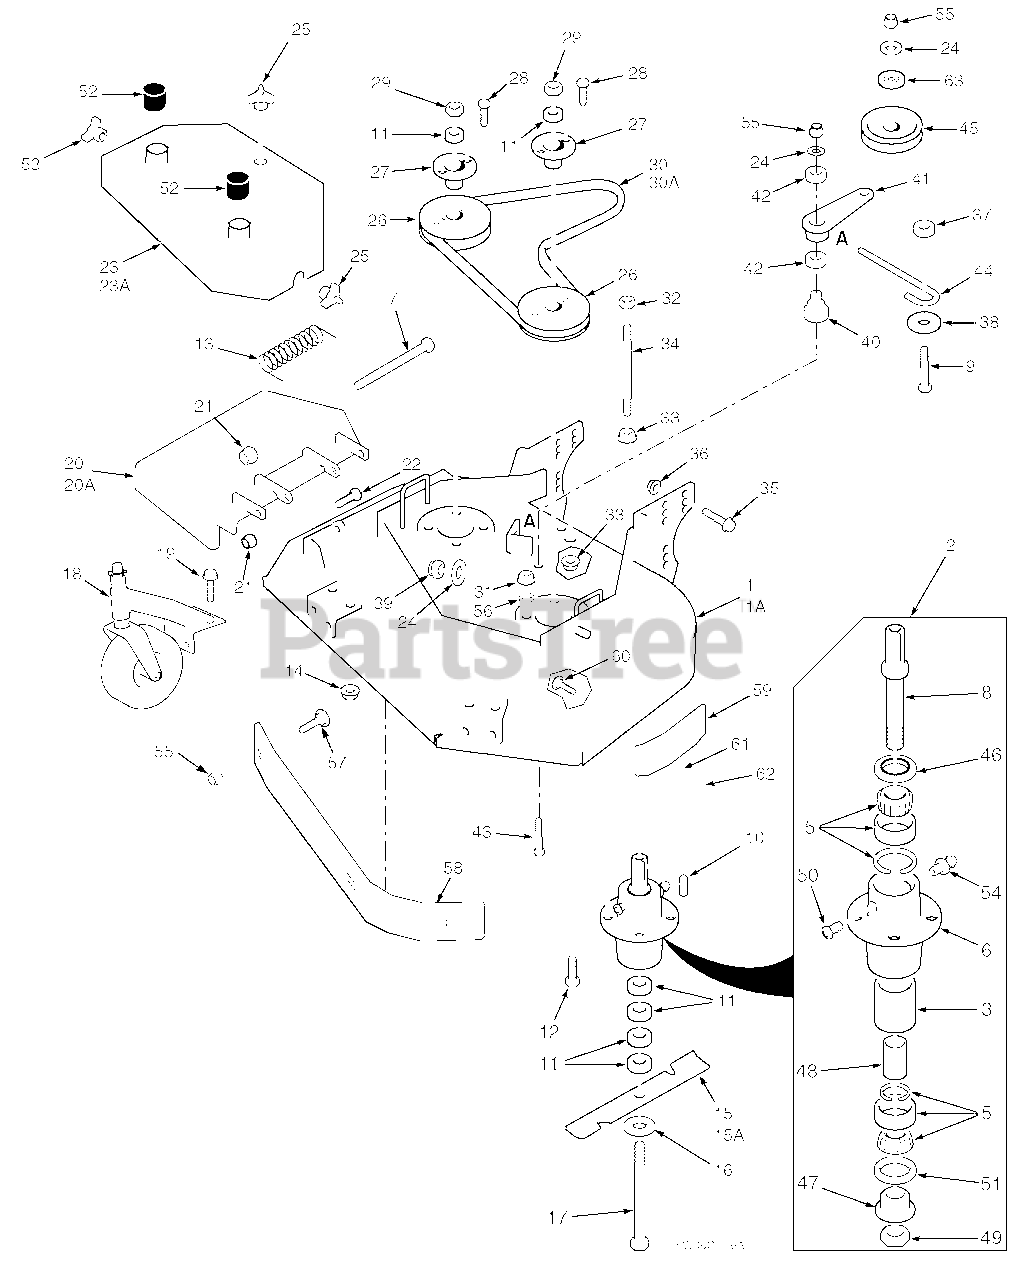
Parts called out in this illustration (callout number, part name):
1	Cutter Deck w/Decals
1A	Cutter Deck w/Decals
2	Cutter Spindle Assembly
3	Spacer, Outside
5	Bearing, Tapered
6	Spindle Housing
7	Bolt, 5/16-18 x 4-3/4"
8	Spindle Shaft
9	Bolt, 3/8-16 x 3-3/4" Hex Head
10	Key, 1/4 x 1/4 x 2"
11	Spacer, Cutter Blade - Small
12	Bolt, 5/16-18 x 1-1/2" Hex Head Grade 8
13	Spring, Chute Return
14	Nut 5/16-18 Serrated Flange
15	Cutter Blade, 16-1/2"
15	Cutter Blade, 18"
15A	Cutter Blade 16-1/2 Hi-Lift
15A	Cutter Blade, 18 Hi-Lift
16	Flatwasher, 5/8 W
17	Hex Hd. Bolt, 5/8-11 x 9-1/2"
18	Caster Assembly
19	Cpscrw,5/16-18 x 3/4" Ser. Flg. Hex Head
20	Discharge Chute
20A	Discharge Chute
21	Hex Nut, 5/16-18 Elastic Stop
22	Hex Hd Bolt, 5/16-18 x 1"
23	Belt Cover Assy
23A	Belt Cover Assy
24	Flat Washer, 3/8" Special
25	Wing Nut, 3/8-16
26	Pulley
27	Tapered Hub
28	Hex Hd. Bolt, 1/4-20 x 1"
29	Hex Nut, 5/8-11
30	Belt, Blade Drive
30A	Belt, Blade Drive
31	Elastic Stop Nut, 5/16-18 Grade 8
32	Hex Nut, 3/8-16 Center Locknut
33	Nut, 3/8-16 Serrated Flange
34	Support, Belt Cover
35	Cpscrw, 1/2-13 x 1"Ser.Flg. HH
36	Nut, 1/2-13 Spiralock
37	Spacer, J-Hook
38	Flatwasher, 3/8 x 1-1/2 x 16 GA
39	Elastic Stop Nut, 3/8-16
40	Idler Pivot
41	Idler Arm Assy.
42	Bearing
43	Cpscrw, 3/8-16 x 3-1/4" Hex Head
44	J-Hook
45	Idler Pulley, Belt Clutch
46	Seal, Cutter Spindle
47	Spindle Bushing
48	Spacer, Inside
49	Nut,1.06-18
50	Relief Fitting, Cutter Spindle
51	Seal, Cutter Spindle
52	Spindle Shield
53	Wing Nut, 3/8-16 (Small) RH side
54	Grease Fitting
55	Nut, Hex Elastic Stop 3/8-16
56	Lock Washer, 5/16"
57	Bolt, Carriage 3/8-16 x 1"
58	Baffle Weldment
59	Pad, Deck Wear
60	Bolt, Carriage 5/16-18 x 3/4"
61	Flatwasher, 5/16"
62	Hex Nut, 5/16-18 Center Locknut
63	Dust Shield
